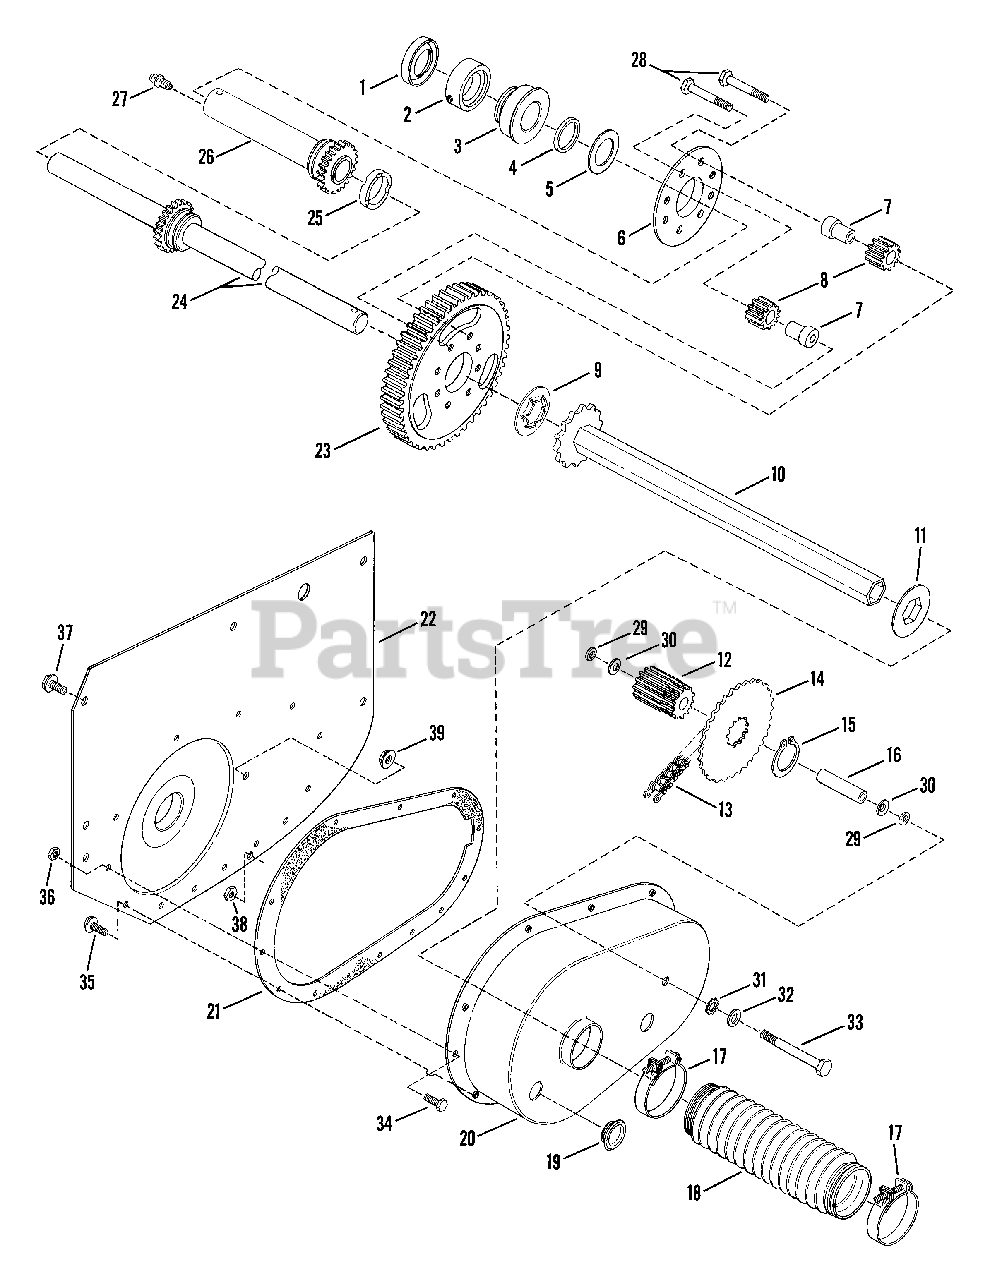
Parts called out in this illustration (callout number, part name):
1	SEAL, Oil
2	COLLAR, Lock
3	BEARING, Axle, Right Hand Fender (1.12" ID 12.5" OD)
4	SPACER, Short Axle
5	WASHER, Thrust
6	PLATE, Differential
7	SPACER, Pinion
8	PINION GEARS, Differential (12 Tooth)
9	WASHER, Thrust
10	ASSEMBLY, Drive Hex Tube
11	WASHER, Nylon Hex Splash
12	GEAR, 11 Teeth, 10 Pitch
13	CHAIN, 46 Pitch (#35)
14	SPROCKET
15	RING, Retaining
16	SPACER
17	CLAMP, Boot
18	BOOT, Oil Seal
19	PLUG, Oil Fill & Check
20	CASE, Transmission
21	GASKET, Transmission Case
22	FENDER, Right Hand
23	GEAR, 63 Teeth, 10 Pitch
24	AXLE, Long
25	SPACER, Differential (1.25" ID x .425 Wide)
26	AXLE, Short
27	FITTING, Lube
28	CAPSCREW, 5/16-24x1 5/8" Hex, Special Lock
29	O-RING, 5/16"
30	WASHER, Belleville
31	WASHER, 5/16 External Tooth Lock
32	WASHER, 5/16 Flat
33	BOLT, 5/16-24x2 5/8" Idler
34	SCREW, 1/4-20x5/8" Hex Head Cap
35	SCREW, 1/4-20x5/8", Self-Tapping
36	NUT, 1/4-20 Hex Lock
37	SCREW, 5/16-18x5/8", Self-Tapping
38	NUT, 5/16-24 Hex
39	NUT, 5/16-24 Hex Flange Lock
